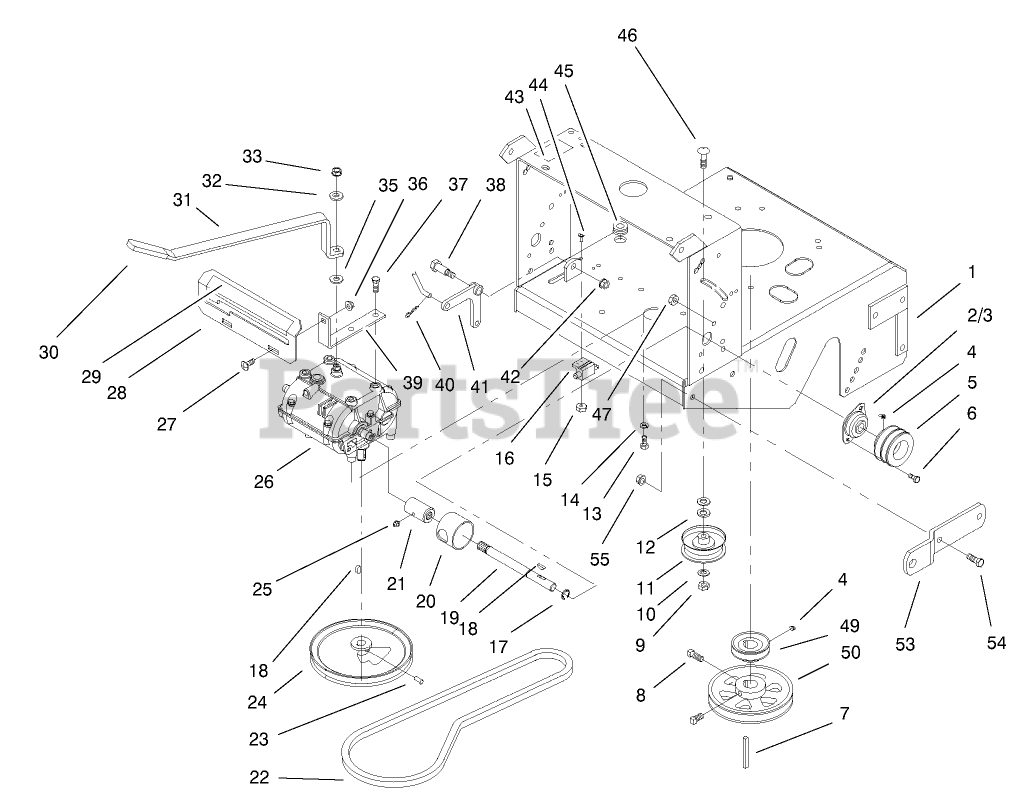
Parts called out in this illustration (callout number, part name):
1	Rear Deck
2	Bearing
3	Flange
4	Screw-Set
5	Sheave
6	SCREW-HH
7	Key
8	SCREW-SET, SQH
9	NUT-LOCK, NI
10	WASHER-FLAT
11	Idler Pulley
12	WASHER-FLAT
13	SCREW-HH
14	WASHER-LOCK
15	NUT-LOCK, NI
16	Switch-Seat
17	Ring-Retaining
18	Key
19	Output Shaft
20	GUARD-COUPLER
21	Coupling
22	Belt-Trans Drive
23	Screw-Set
24	Sheave
25	FITTING-GREASE
26	Transmission
27	BOLT-CARR
28	Shifter Plate
29	DECAL-SPEED, GROUND
30	Grip
31	Lever-Shift
32	Washer
33	NUT-LOCK
35	Washer
36	NUT-HF
37	SCREW-HWH
37	SCREW-HWHTF
38	Bolt-Shoulder
39	Leg-Shifter Lever
40	PIN-COTTER
41	Bell Crank
42	NUT-HHF, WHIZ
43	DECAL-SHUT OFF, FUEL
44	Screw
45	Grommet-Fuel Line
46	Bolt-CARR
47	NUT-LOCK, NI
49	Sheave
50	Pulley-Blade Drive
52	Rivet
53	Hitch Bracket
54	SCREW-HH
55	NUT-HHF, WHIZ
